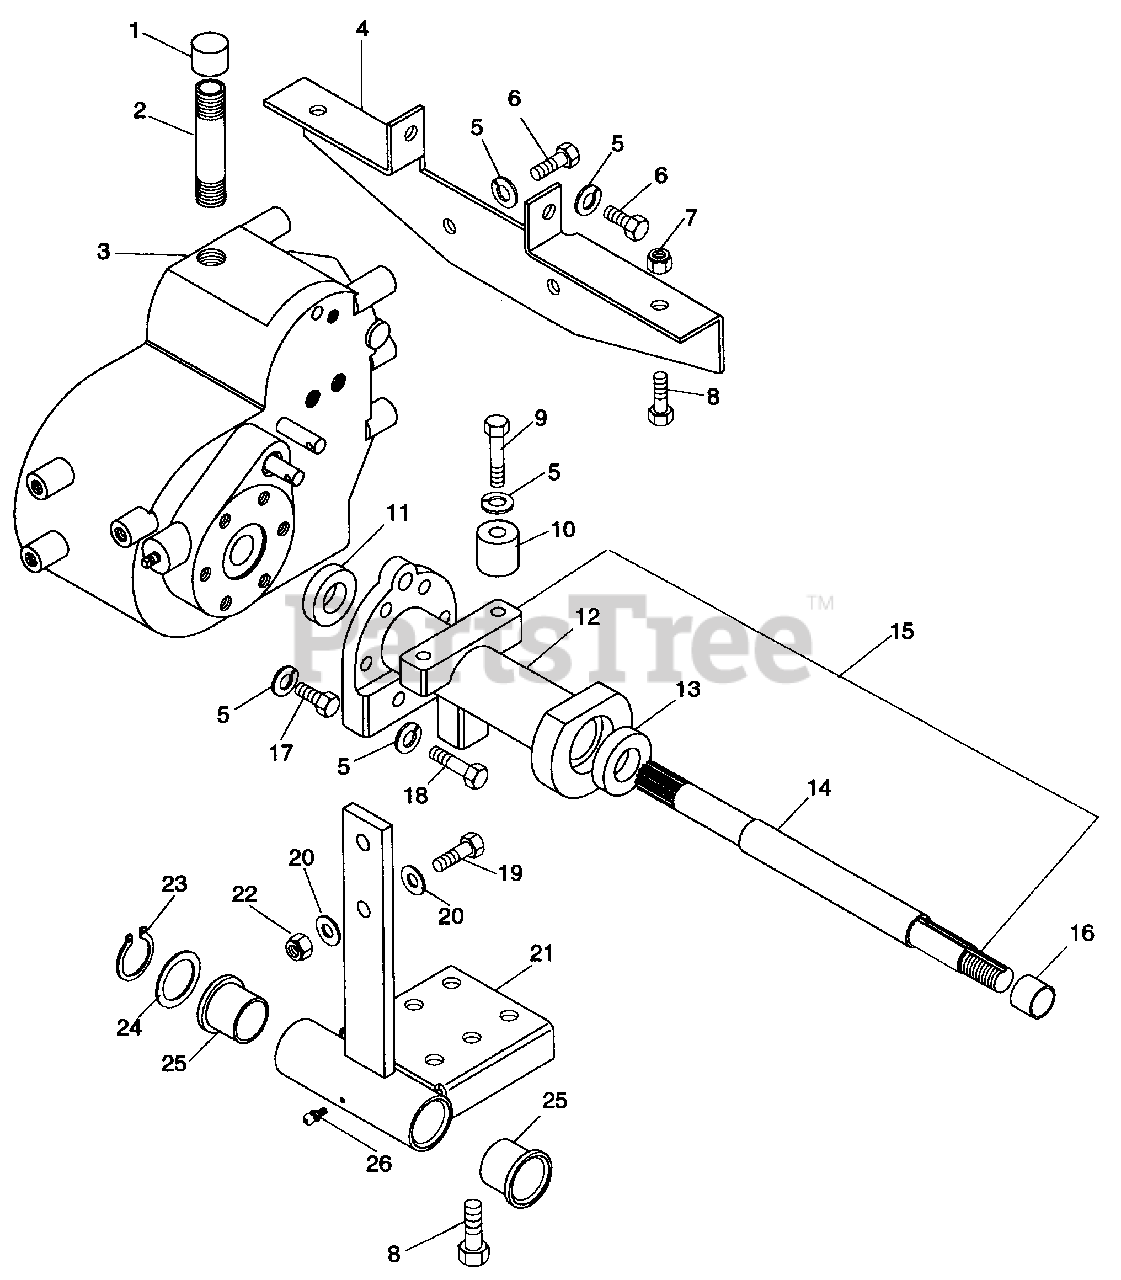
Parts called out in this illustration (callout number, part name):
1	CAP, PIPE .75 UNFIN MAL IR
2	NIPPLE, PIPE .75 X 5.0 UNFIN STL
3	TRANSAXLE
4	PLT, TRANSAXLE
5	WSHR-LOCK .50 REG.
6	BLT-HEX .50-13 X 1.25 PL GR 5
7	NUT-LK-NYL .625-11 PL
8	BLT-HEX .625-11 X 1.50
9	BLT-HEX .50-13 X 2.75 PL GR 5
10	SPCR, FRAME
11	RING, ALIGNMENT
12	HOUSING, AXLE
13	BRG, BALL 1.18 X 2.440 X .629
14	AXLE
15	ASM, AXLE HOUSING
16	SPCR, AXLE 1.75 X .800 ST
17	BLT-HEX .50-13 X 1.50 PL GR 5
18	BLT-HEX .50-13 X 2.25 PL GR 5
19	BLT-HEX .50-13 X 1.75
20	WSHR-FL-STL .531 X 1.062 X .095
21	WLDMT, PIVOT BRKT
22	NUT-LK-NYL .50-13 PL
23	RING, RETAINING
24	WSHR-THRST 1.50 X 2.18 X .063
25	BSHG-FLG 1.154 X 1.756 X 1.688 X 2.2
26	FTG., LUBE; .25-28 SELF-THREAD
